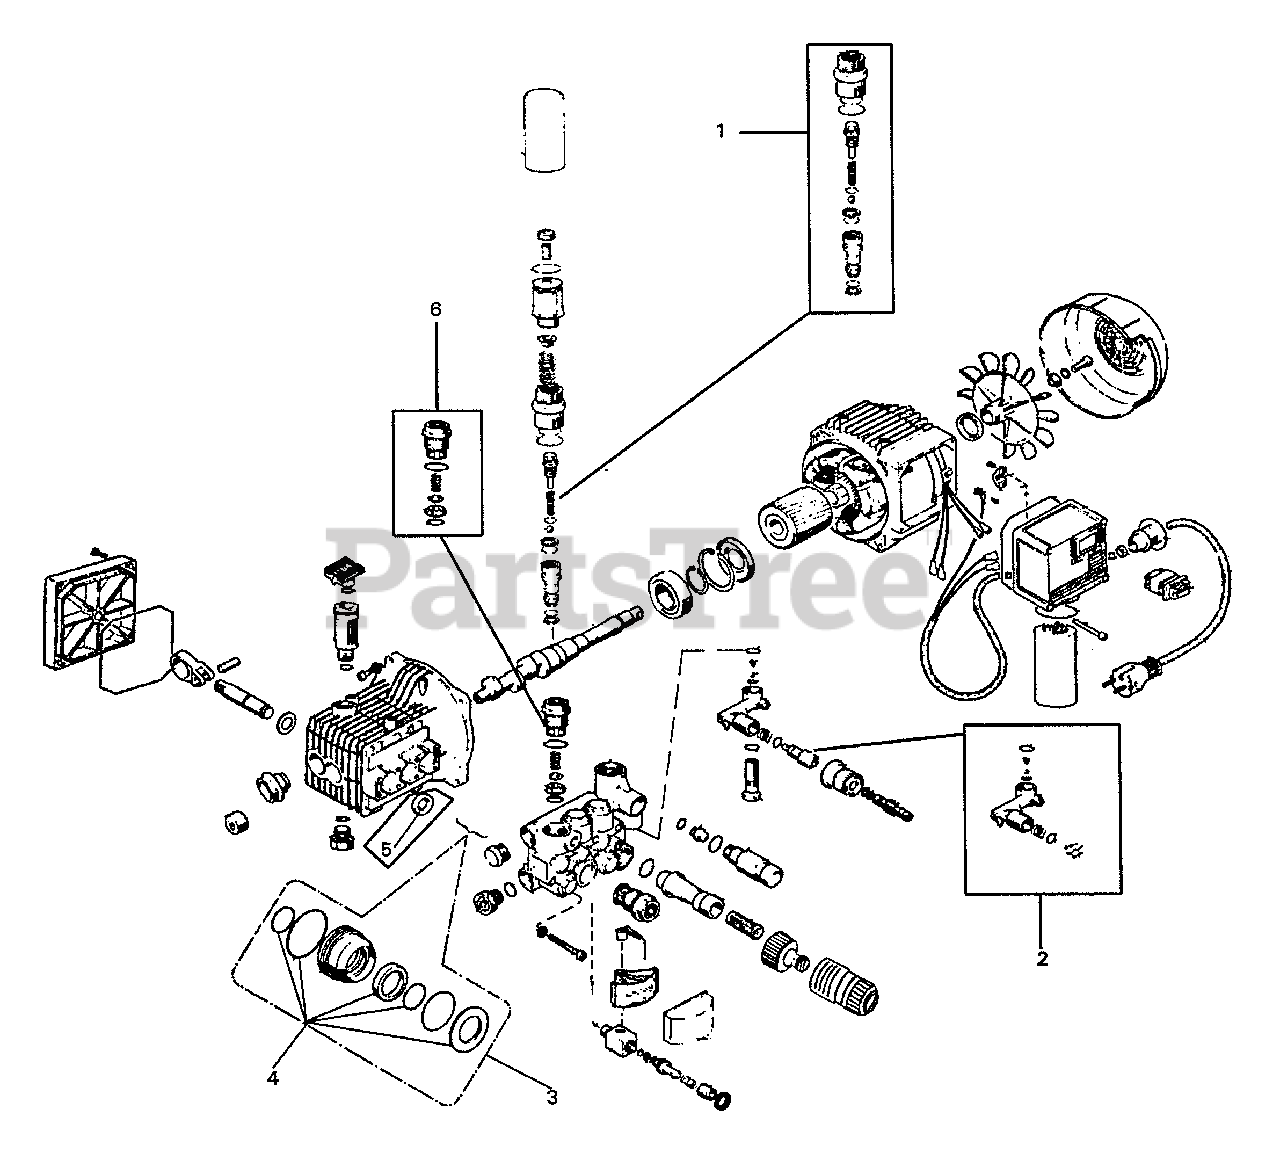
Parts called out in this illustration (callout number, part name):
1	VALVE KIT
2	REBUILD RETAINER PACKING KIT
3	RETAINER REBUILD PACKING KIT
4	PACKING KIT
5	SEAL ASSY, OIL
6	VALVE KIT
